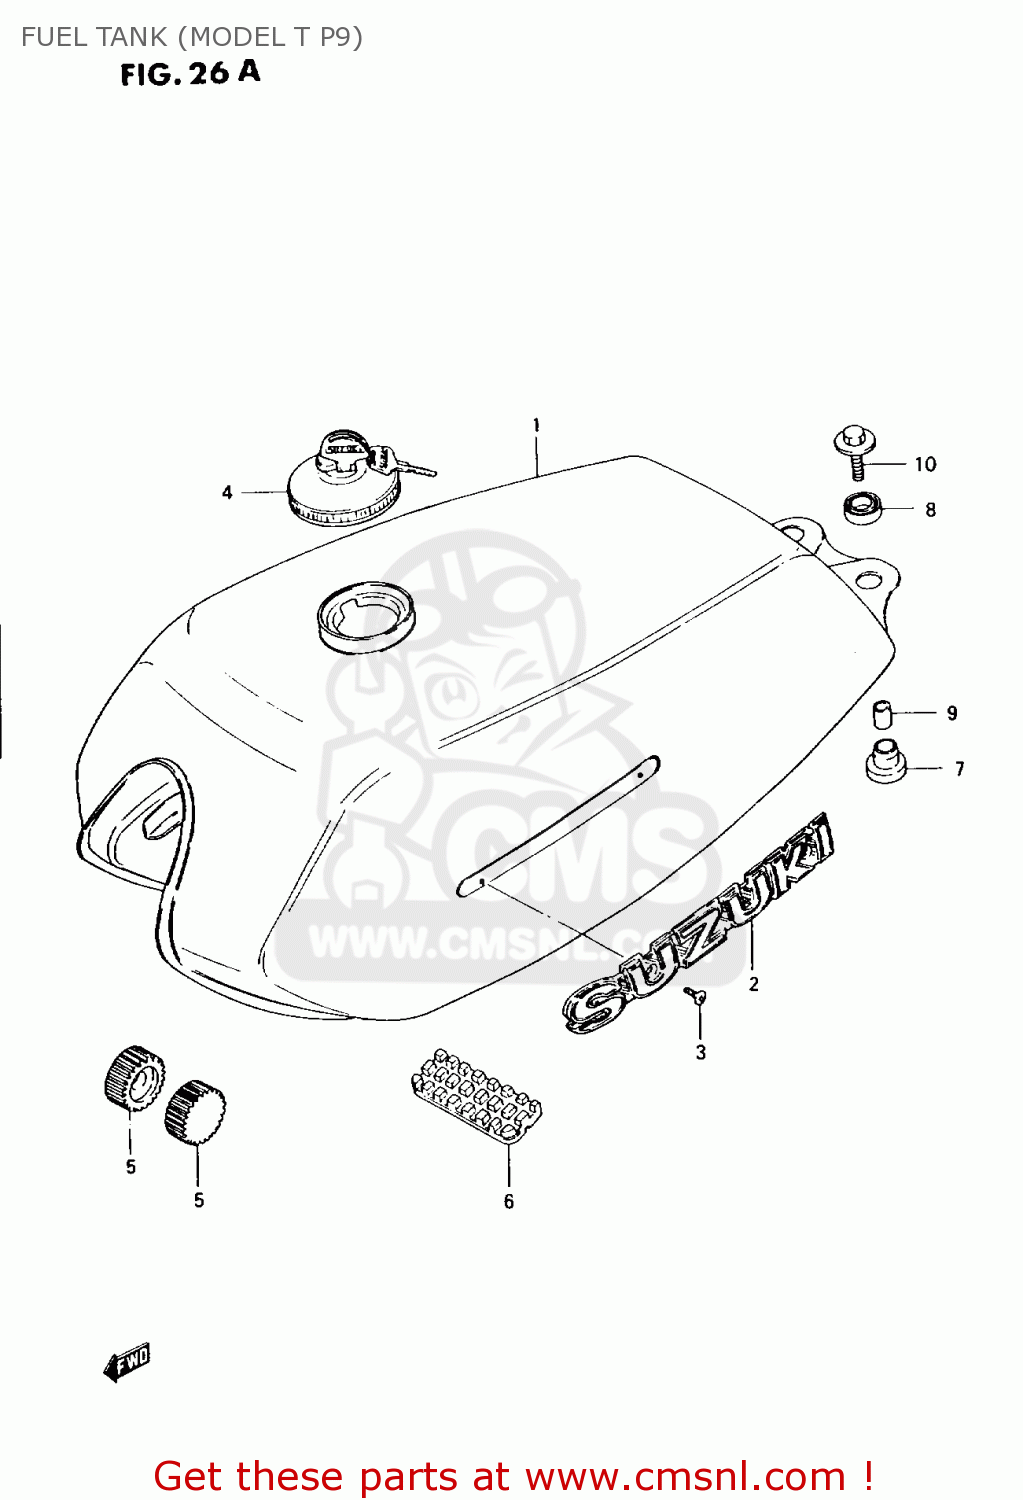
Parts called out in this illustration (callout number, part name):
1	TANK ASSY, FUEL
2	EMBLEM,FUEL TANK
3	SCREW
4	CAP SET,FUEL TANK
5	CUSHION
6	CUSHION
7	CUSHION
8	CUSHION
9	SPACER(6.5X9X18)
10	BOLT(6X30)
